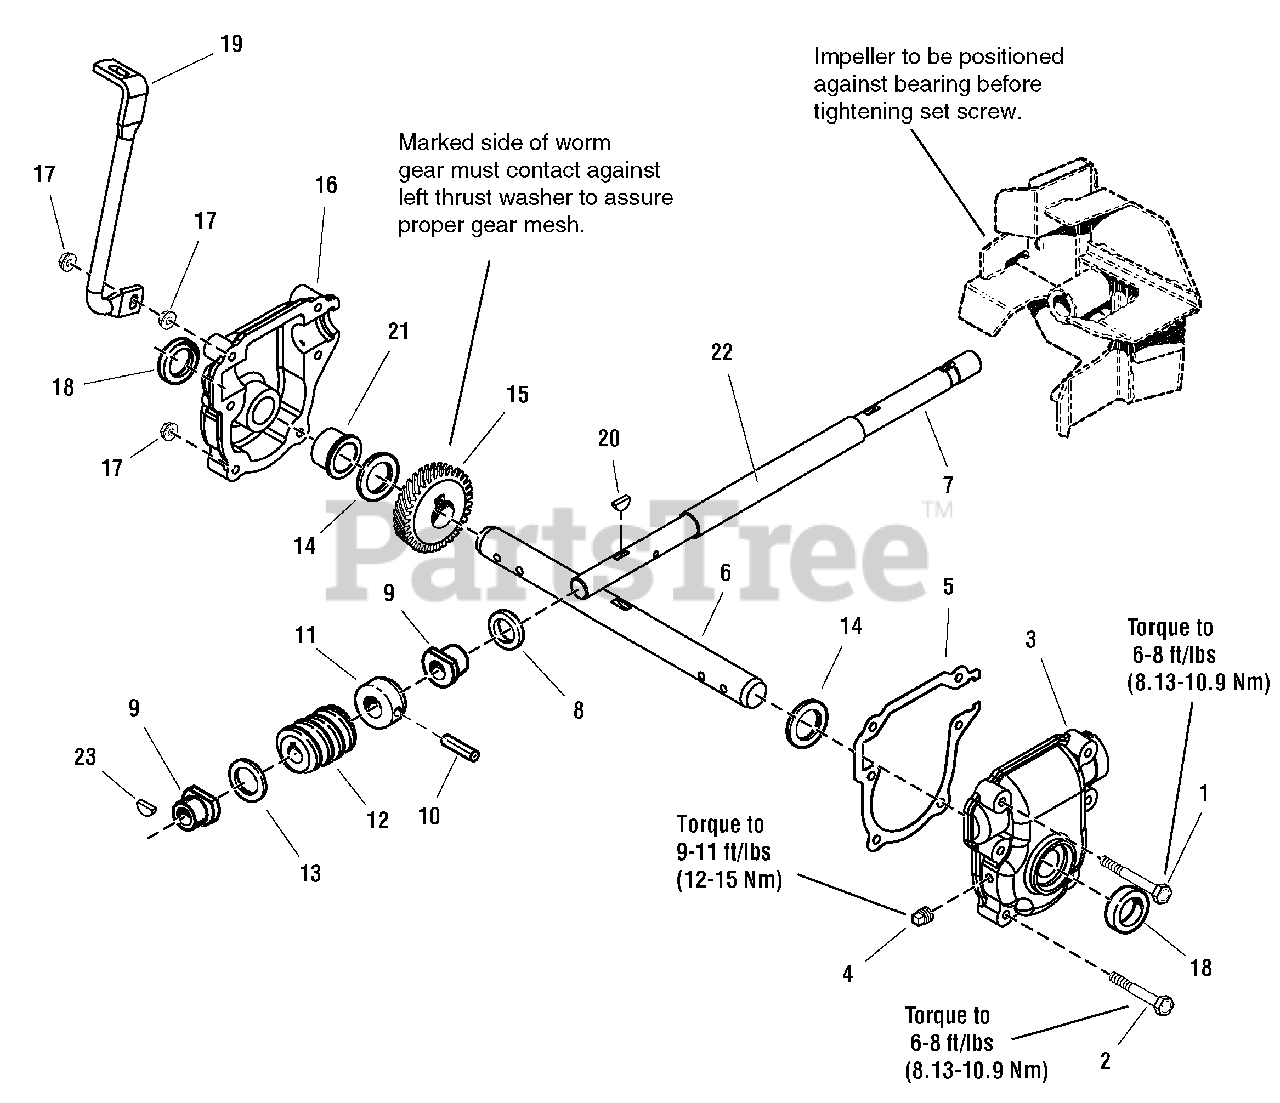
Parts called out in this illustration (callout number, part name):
1	CAPSCREW, Hex Head, 1/4-20 x 2-1/2
2	CAPSCREW, Hex Head, 1/4-20 x 2-1/4
3	GEAR CASE, L.H.
4	FITTING, Pipe Plug
6	SHAFT, Auger Cutoff
7	SHAFT, Worm Cutoff
9	FLANGE BUSHING
10	PIN, Drive Lock
11	THRUST COLLAR
12	WORMGEAR, 1-3/4 OD x 1-3/8 Long
13	THRUST WASHER
14	THRUST WASHER
15	WORMGEAR, 21T, 3" O.D. x 7/8 Long
16	GEAR CASE, R.H.
17	NUT, Top Lock Flange 1/4-20
19	BRACKET, Support
20	KEY, Woodruff .18 x .62
23	KEY, Woodruff 1/4 x 3/4
